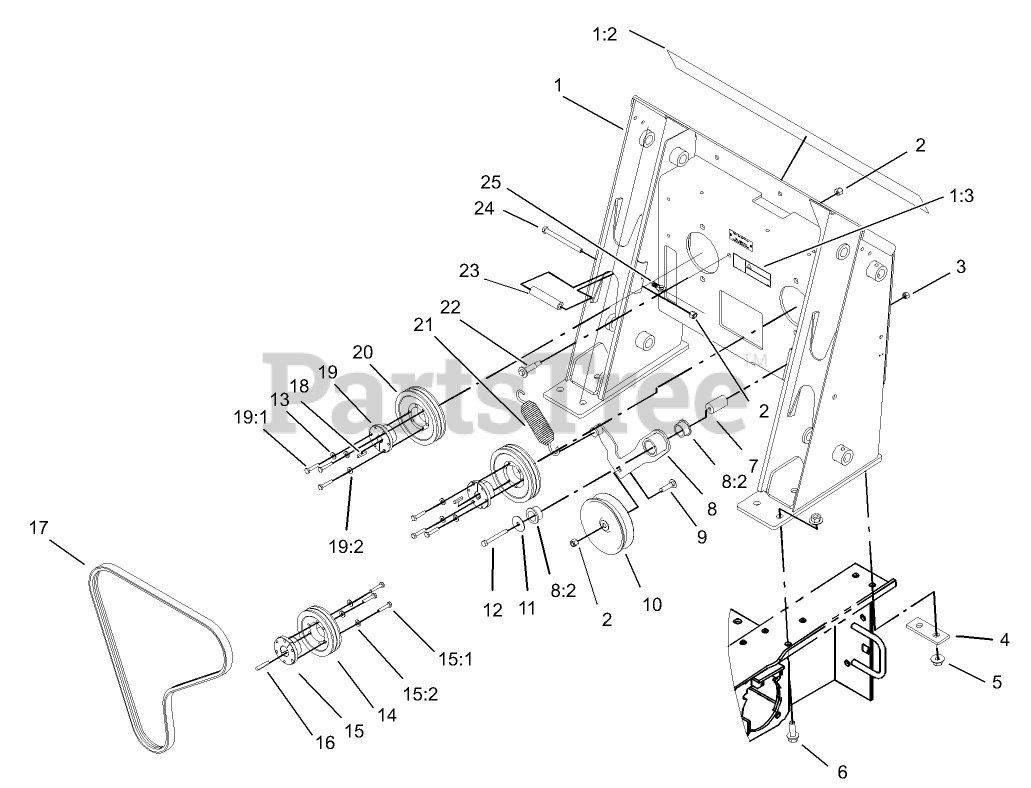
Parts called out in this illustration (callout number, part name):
1	LOADER TOWER ASM
1:2	DECAL-PANEL
1:3	DECAL-WARNING
2	NUT-LOCK, NI
3	NUT-LOCK, NI
4	PLATE-STIFFENER
5	NUT-LOCK, FLANGE
6	SCREW-HHF
7	SPACER-MOUNTING
8	IDLER ARM ASM
8:2	BUSHING-FLANGE
9	SCREW-CARR
10	PULLEY-IDLER
11	WASHER-FLAT
12	SCREW-HH
13	WASHER-FLAT
14	PULLEY
15	BUSHING
15:1	SCREW-HH
15:2	WASHER-LOCK / SP
16	KEY-SQUARE
17	V-BELT
18	KEY-PUMP
19	BUSHING
19:1	SCREW-HH
19:2	WASHER-LOCK / SP
20	SHEAVE
21	SPRING-EXTENSION
22	BOLT-WHEEL
23	TUBE-SPACER
24	SCREW-HH
25	LATCH ASM
